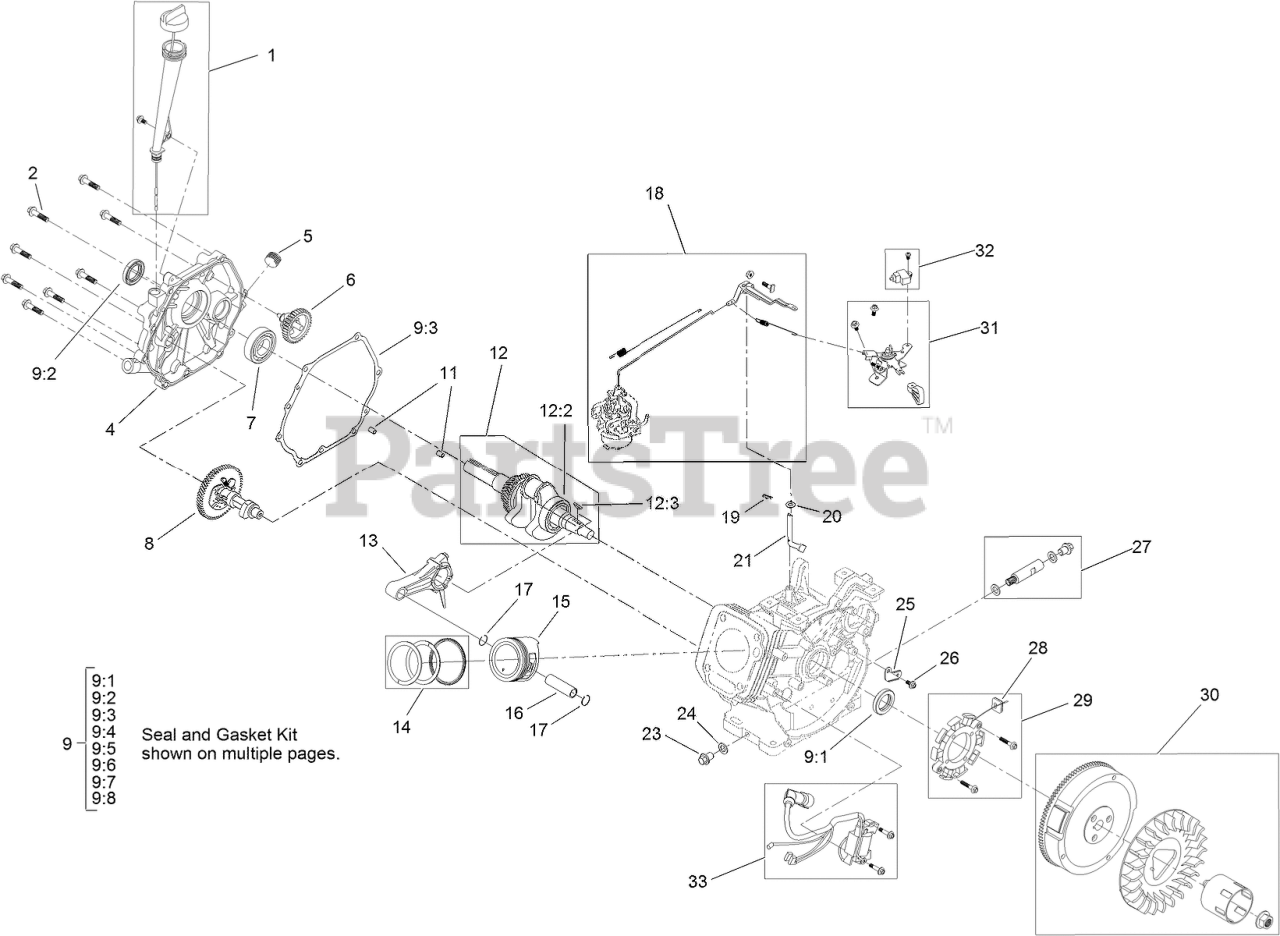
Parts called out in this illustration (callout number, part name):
1	OIL FILL KIT
2	SCREW-HHF
4	COVER-CRANKCASE
5	Plug-Drain
6	GOVERNOR GEAR ASM
7	BEARING-MAIN
8	CAMSHAFT ASM
9	SEAL AND GASKET KIT
9:1	SEAL-OIL
9:2	SEAL-OIL
9:3	GASKET-COVER, CRANKCASE
9:4	GASKET-HEAD, CYLINDER
9:5	GASKET-COVER, VALVE
9:6	GASKET-EXHAUST
9:7	GASKET-CARBURETOR
9:8	GASKET-CARBURETOR
11	PIN-DOWEL
12	CRANKSHAFT ASM
12:2	BEARING-MAIN
12:3	KEY-WOODRUFF
13	CONNECTING ROD ASM
14	SET-RING, PISTON
15	PISTON
16	PIN-PISTON
17	CLIP-PIN, PISTON
18	COMPLETE GOVERNOR KIT
19	PIN-HAIR
20	WASHER-PLAIN
21	SHAFT-GOVERNOR
23	SCREW-HHF
24	WASHER-PLAIN
26	SCREW-HHF
27	DRAIN PLUG KIT
28	GROMMET-RUBBER
29	STATOR KIT
30	FAN AND FLYWHEEL KIT
31	THROTTLE CONTROL KIT
32	KILL SWITCH KIT
33	IGNITION MODULE KIT
